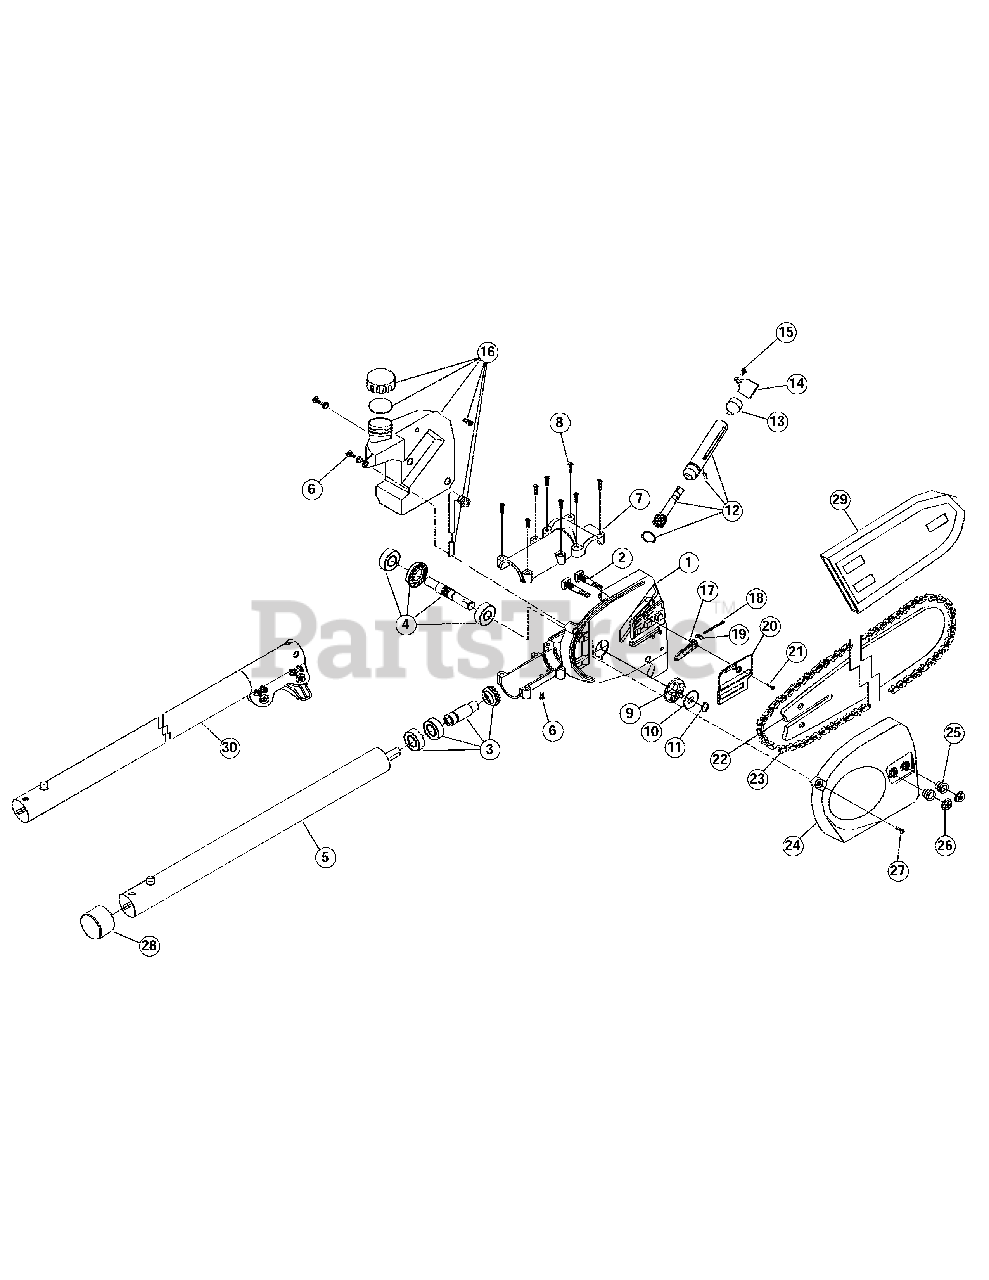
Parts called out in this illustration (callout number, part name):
1	Gearbox
3	Shaft Assembly
4	Spindle Assembly
5	Connection Stick Assembly
7	Case Cover
9	Sprocket
10	Washer
11	C Ring
12	Oil Pump Assembly
13	Rubber Cork
14	Fixed Plate
16	Oiler Assembly
17	Anti-Spillage Pad
18	Regulation Screw
19	Regulation Cap
20	Adjustable Plate
22	Bar 8"
23	Saw Chain
25	Fixed Ring
26	Nut
28	Covering
30	Inner Pipe Assembly
